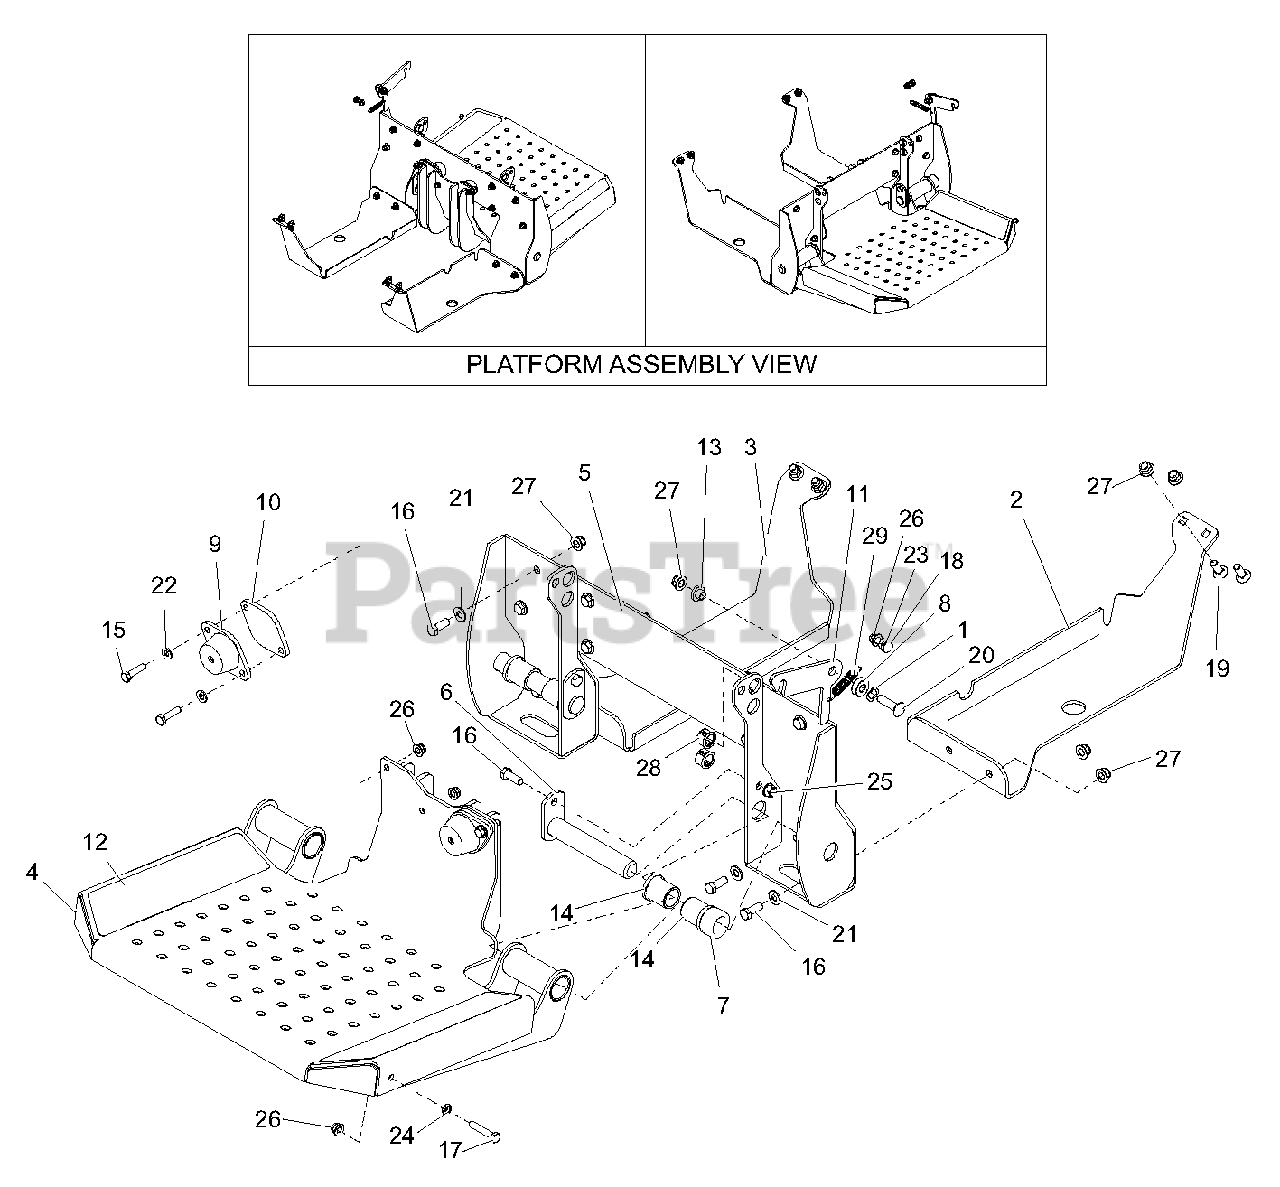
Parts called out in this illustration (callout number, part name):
1	WAVE WASHER .531 X .781 X .125 FH
2	PLATE, TRANS SKID RH
3	PLATE TRANS SKID LH
4	WLDMT OPERATOR PLATFORM
5	WLDMT BRKT PLATFORM MOUNTING
6	WLDMT PIN PLATFORM MTG
7	SPCR, 1.00 X 1.5 X 0.75
8	SPCR, .375 X 1.00 X .342
9	MOUNT VIBRATION ISO
10	PLATE SPR ISOLATOR PLATFORM
11	PLATE LATCH PLATFORM PROSTAN
12	GRIP, ADHESIVE PRO-STANCE
13	BSHG-FLG .385 X .500 X .875 X .406 REV
14	BSHG FLG 1.00 X 1.25 X 1.5 X 1.5
15	BLT HEX .31-18 X 1.25 GR5 YWZC
16	BLT HEX .38-16 X 1.00 GR5 YWZC
17	BLT HEX .31-18 X 1.75 GR5 YWZC
18	BLT RDHDSQNK .31-18 X .25 G5 Y
19	BLT RDHDSQNK .38-16 X 1.00 G5 YWZC
20	BLT RDHDSQNK .38-16 X 1.50 G5 Y
21	WSHR FL STL .406 X .812 X .065 YWZ
22	WSHR FL STL .344 X .688 X .065 YWZC
23	NUT SPNLK FLG .312-18 YWZC
24	NUT 5/16-18 JAM GR5
25	NUT LK TOP FLG .38-16 YWZC
26	NUT LK NYL FLG .31-18 YWZC
27	NUT LK NYL FLG .38-16 YWZC
28	BUSH, PANEL SNAP .687 X .875 X .56
29	SPRG, EXTENSION
